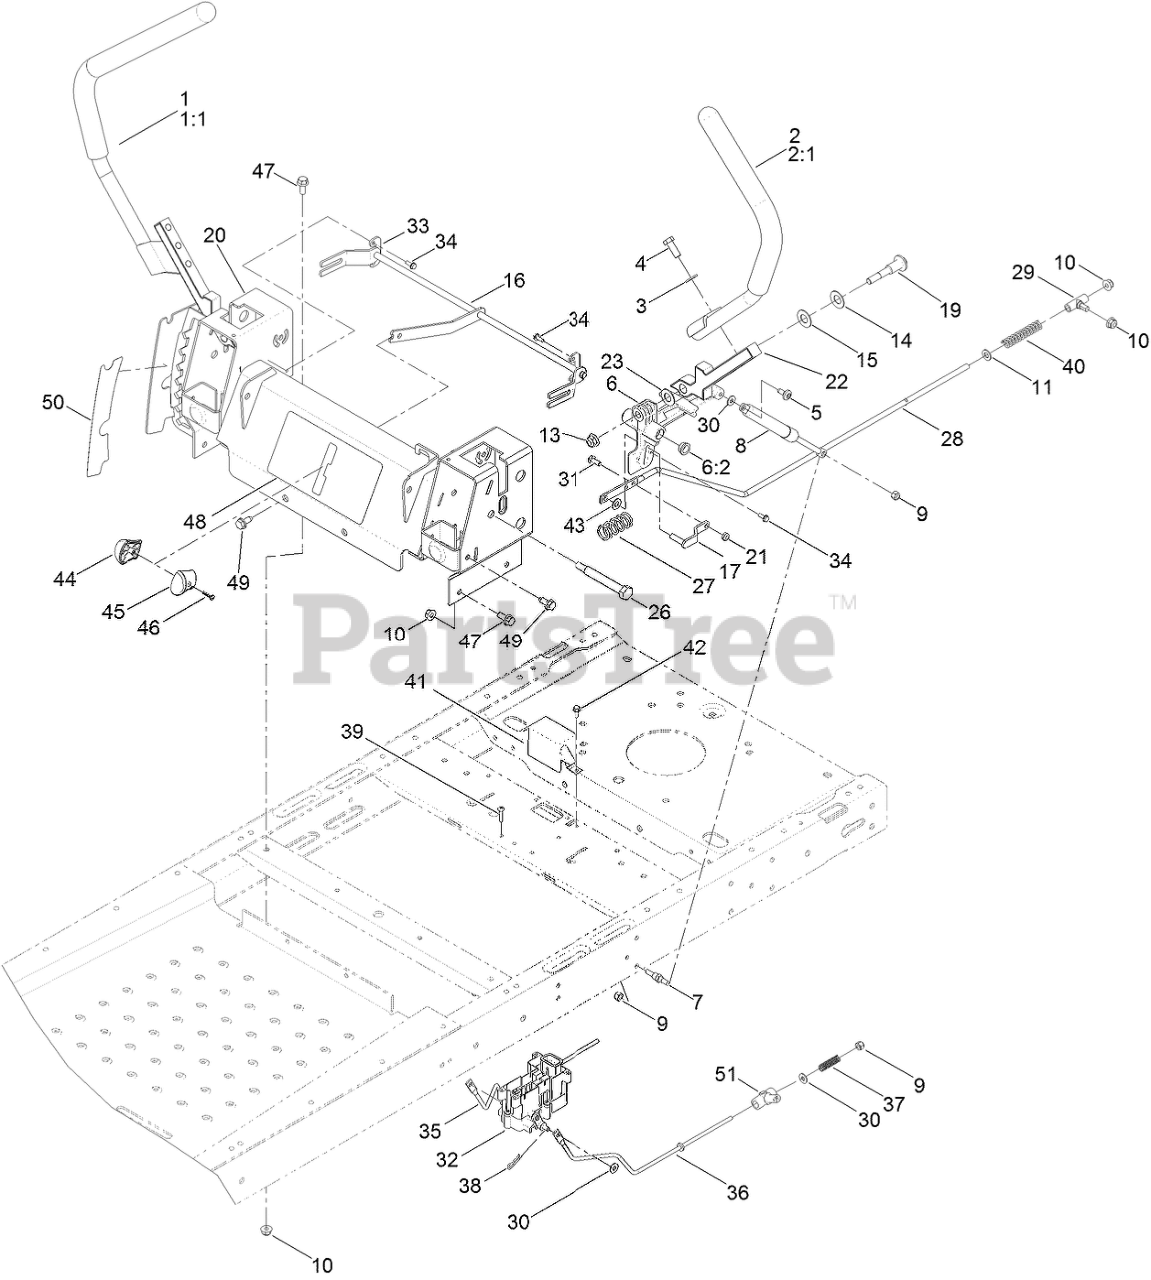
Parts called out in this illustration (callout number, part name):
1	HANDLE-CONTROL, RH
2	HANDLE-CONTROL, LH
3	WASHER-FLAT
4	SCREW-HH
5	SCREW-SHOULDER
6	ACTUATOR ARM ASM
6:2	BUSHING-FLANGE
7	STUD-DAMPER
8	Damper-Control, Motion
9	NUT-LOCK, NI
10	NUT-HF, NI
11	WASHER-PLAIN
13	NUT-HF, NI
14	WASHER-BELLEVILLE
15	WASHER
16	CONTROL-SPEED
17	PIN-ROD, HYDRO
19	BOLT-PIVOT
20	CONTROL BOX ASM
21	NUT-LOCK, NI
22	LEVER-CONTROL
23	WASHER-NYLON
26	BOLT-PIVOT
27	SPRING-RETURN
28	ROD-HYDRO
29	MOUNT-ROD, HYDRO
30	WASHER
31	SCREW-HH
32	BRAKE CONTROL MODULE ASM
33	RETAINER
34	SCREW-TAPTITE
35	ROD-BRAKE, RH
36	ROD-BRAKE, LH
37	SPRING-COMPRESSION
38	PIN-COTTER
39	SCREW-PPH
40	SPRING-RETURN, NEUTRAL
41	COVER-BRAKE
42	SCREW-HWH
43	SPACER-NYLON
44	KNOB-RH
45	KNOB-LH
46	SCREW-PPH
47	SCREW-HHF
48	DECAL-SPEED CONTROL
49	SCREW-HWHTF
50	DECAL-HOC
51	MOUNT-PIVOT
